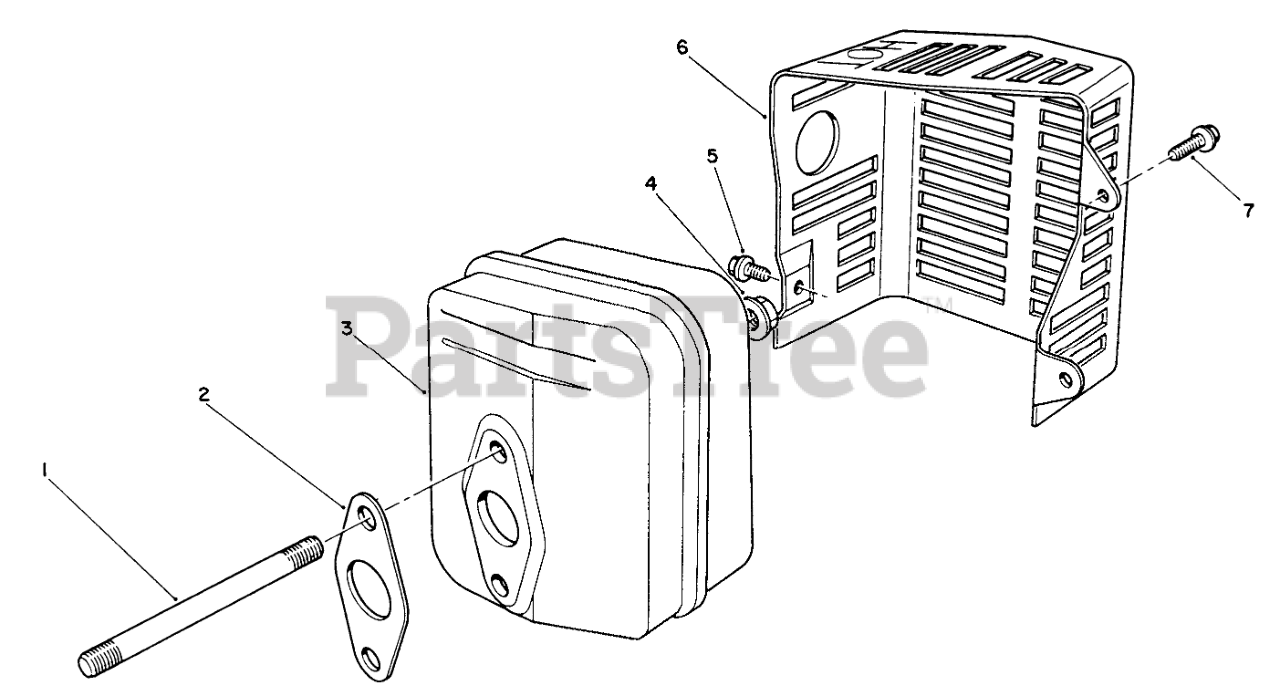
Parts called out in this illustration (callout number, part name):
2	GASKET
3	MUFFLER
5	SCREW
6	COVER
